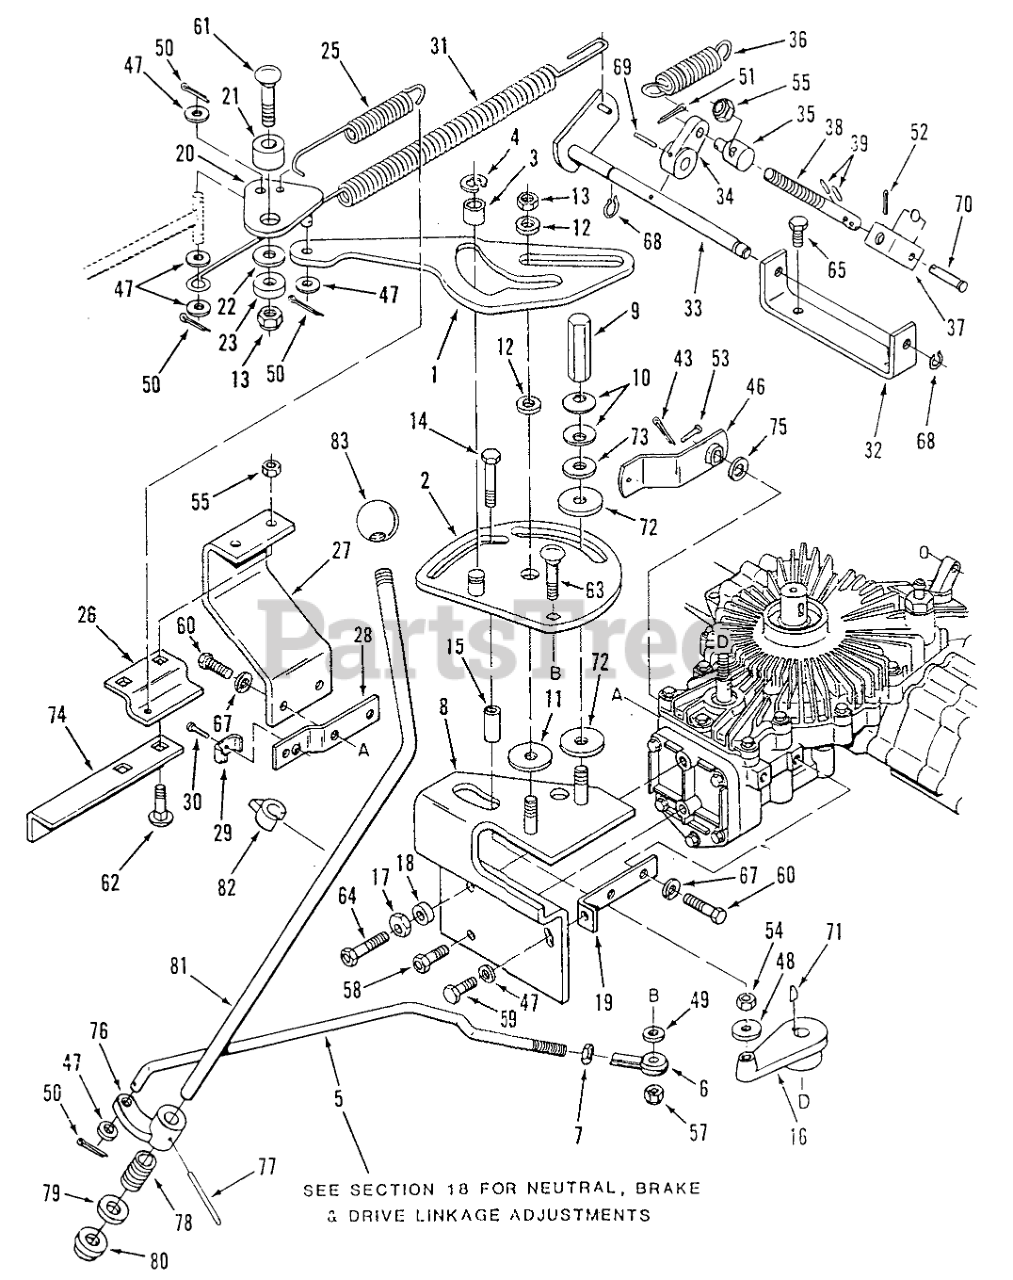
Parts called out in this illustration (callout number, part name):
1	NEUT-RETURN PLATE
2	ASS'Y-CAM PLATE
3	BEARING-CAM RETURN
4	E Ring
5	ROD-SPEED CONTROL
6	ASSY ROD END
7	Jam Nut 1/4-28
8	ASS'Y-CAM PLATE S R
9	NUT-SPECIAL 3/8 X 2"
10	WASHER-SPRING DISC
11	FRICTION WASHER
12	CAM-SPACER
13	NUT-HEX, JAM
14	Bolt 1/4-20 X 1 1/2
15	SPACER
16	ARM MOTION CONTROL
18	SPACER-GEAR
19	ASS'Y-ANGLE SUPPORT
20	PIVOT PLATE ASSY R
21	SPACER
22	WASHER-SPECIAL
23	SPACER-LIFT LINK
25	SPRING-RETURN
26	BRACKET R
27	BRACKET-TORQUE R
28	MAIN-HARNESS & DIAG
29	CLAMP THROTTLE
30	HWHTRS 10-24 X 1/2
31	SPRING-BRAKE
32	BRACKET
33	ASS'Y-BRAKE PIVOT
34	PLATE
35	TRUNNION-CLUTCH ROD
36	SPRING-BRAKE
37	CLEVIS R
39	PIN SPIROL
43	Cotter Pin
46	Plate
47	WASHER 5/16 SAE
48	Washer
50	Cotter Pin
51	Cotter Pin
52	Cotter Pin
54	Nut
55	Nut
57	Nut
58	Screw
59	Bolt
60	Bolt
61	Bolt
62	Bolt-Carriage
63	Carriage Bolt 1/4-20 x 1
64	Bolt
65	Bolt
67	Lockwasher
68	EXTERNAL SNAP RING
69	Pin-Roll
71	KEY WOODR 1/8X1/2 DI
72	WASHER-FRICTION
73	Washer
74	BRACKET R
75	Washer
76	ARM SHIFTER B
77	SPIROL PIN 7/32X21/2
78	SPRING COMPRESSION
79	Washer
80	BUSHING-NYLINER
81	ROD SHIFT LEVER
82	POINTER
